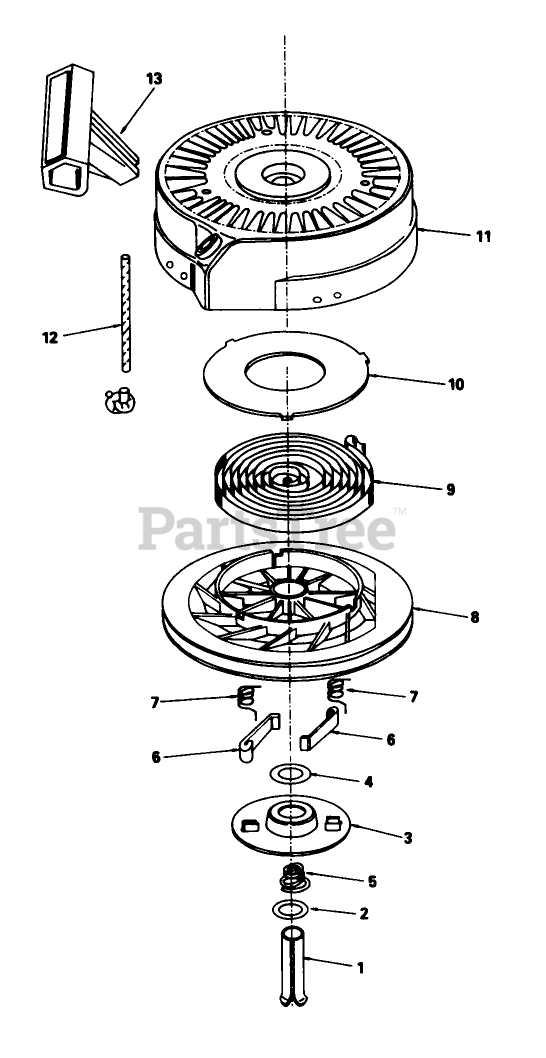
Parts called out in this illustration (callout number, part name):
1	Pin, Spring (Incl. Ref. #7)
2	Washer
3	Retainer
4	Washer
5	Brake Spring
6	Dog-Starter
7	Spring-Dog
8	Pulley
9	Rewind Spring
10	Cover-Spring
11	Housing-Starter
12	Rope-Starter (98 cut to length)
13	Handle-Starter
